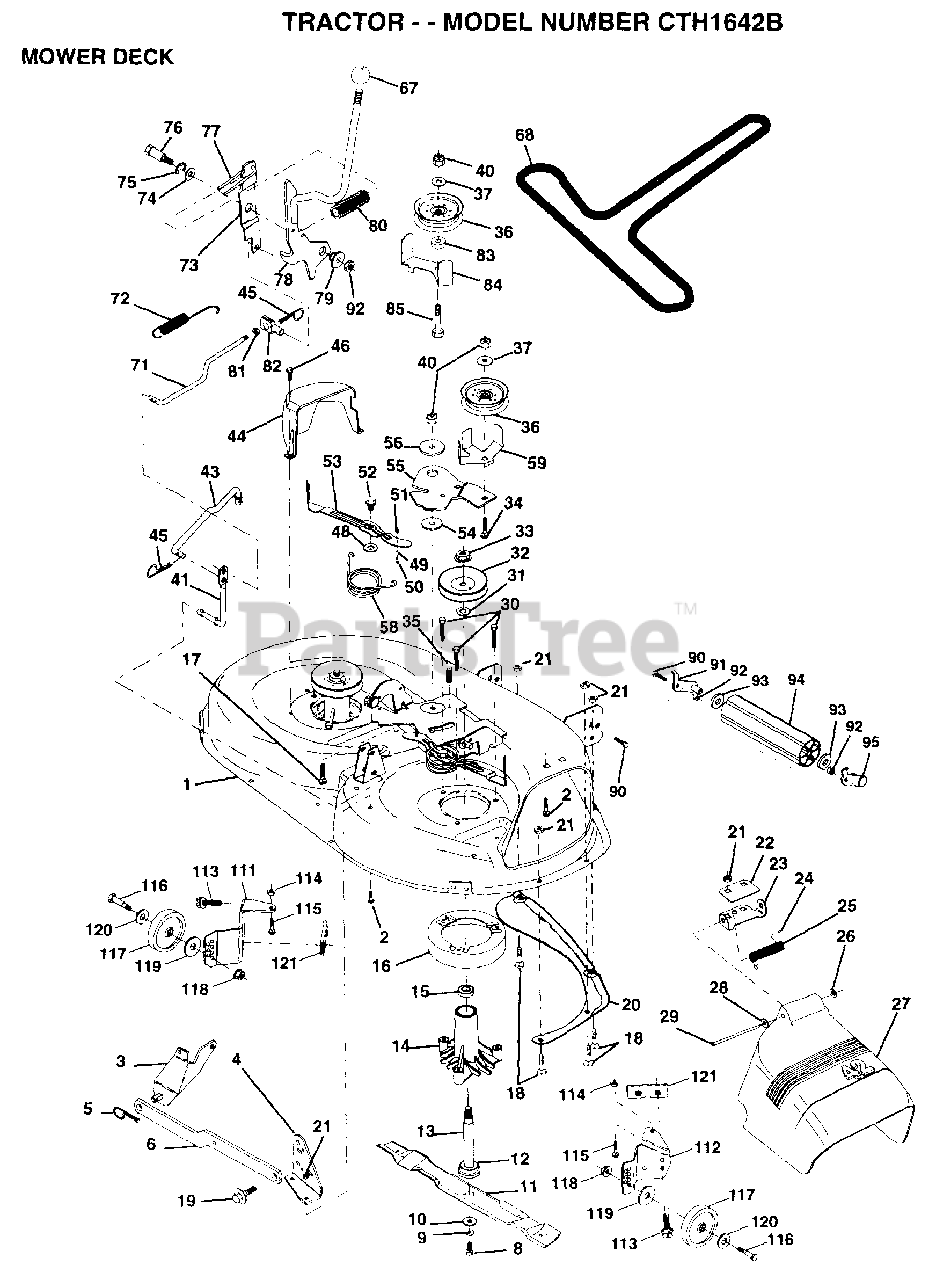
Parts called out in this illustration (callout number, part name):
1	DECK.WELD.42.
2	BOLT
3	BRKT ASM SWAY BAR
4	BRKT DECK SW BAR
8	BLADE BOLT
10	WASHER.HARD.BLADE
11	"BLADE.42"" HIPERF"
12	BEARING.BALL
14	HSG ASM MANDREL
15	BEARING
16	STRIPPER RND MWR
17	BOLT RDHD 3/8-16
18	BOLT
19	BOLT SHD 5/16-18
22	STIFFENER BRKT
23	DEFLECTOR BRKT
24	CAP-SLEEVE LT
25	SPRING TORSION
26	NUT PUSH M
27	DEFLECTOR.SHIELD
28	WASHER
29	HINGE ROD
31	WASHER
34	BOLT
35	XMAS TREE FASTNER
36	FLAT IDLER PULLEY
37	WASHER
41	PIVOT ROD
43	ROD CLUTCH W/NIBS
44	GUARD MAND LH BLK
45	RETAINER M
46	SCREW.1/4-20X5/8
48	HARD SMALL WASHER
50	SHOULDER BOLT
51	LOCKNUT
52	BOLT.SHLD.5/16-18
53	BRAKE PAD ARM ASM
54	HARDENED WASHER
56	SPACER RETAINER
58	SPRING TORSN BRAK
59	GUARD IDLER TUV
68	BELT.V.T-PATH
71	ROD CLUTCH 38/42
72	RETURN SPRING
73	CLUTCH ARM SECOND
74	WASHER
75	RING
76	SHOULDER BOLT
77	SPRING KEEPER
78	LEVR ASM CLUTCH
79	BUSHING
81	NUT
82	TRUNION ADJ
83	WASHER
85	BOLT RDHD 3/8-16
90	BOLT
92	NUT
93	WASHER
113	SCREW
116	BOLT M
117	WHEEL.GAGE.BLK.PL
118	LOCKNUT
119	WASHER
120	WASHER
121	BRACKET.EXTRD.GWL
